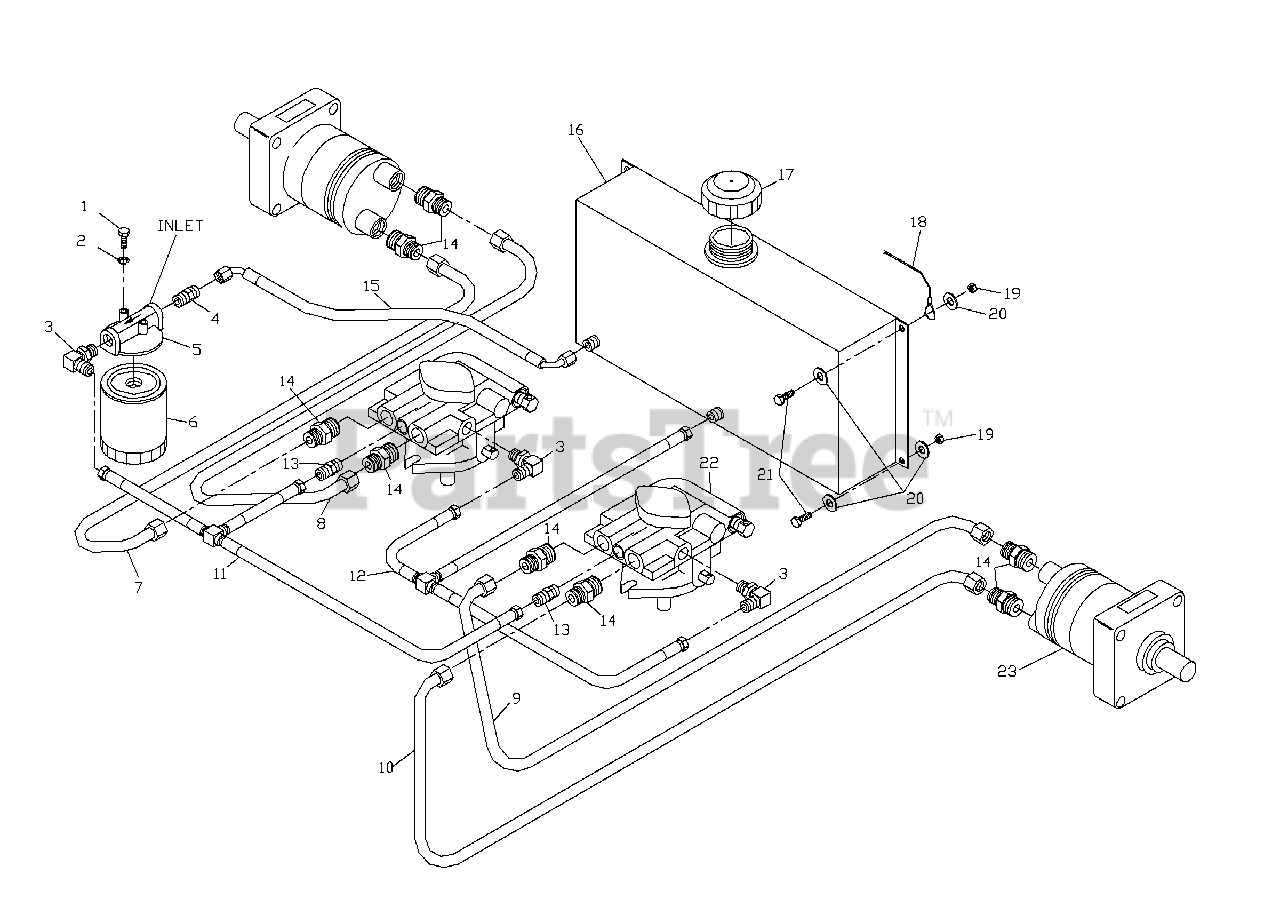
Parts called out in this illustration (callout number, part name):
1	HCS 1/4C X 5/8
2	1/4" LOCKWASHER
3	F6801-6-6-0 90 DEG. ELBOW
4	F6400-6-6-0 STRAIGHT FITTING
5	FILTER HEAD
7	RIGHT OUTSIDE TUBE
8	RIGHT INSIDE TUBE
9	LEFT INSIDE TUBE
10	LEFT OUTSIDE TUBE
11	SUCTION TEE ASSEMBLY
12	RETURN TEE ASSEMBLY
13	F6400-6-4-0 STRAIGHT FITTING
14	F6400-8-8-0 STRAIGHT FITTING
16	TANK, HYDRAULIC
17	HYDRAULIC CAP
18	SEAT LANYARD
19	NUT 1/4C CENTERLOCK
20	WASHER 1/4 FLAT
21	HCS 1/4C X 1
23	WHEEL MOTOR
